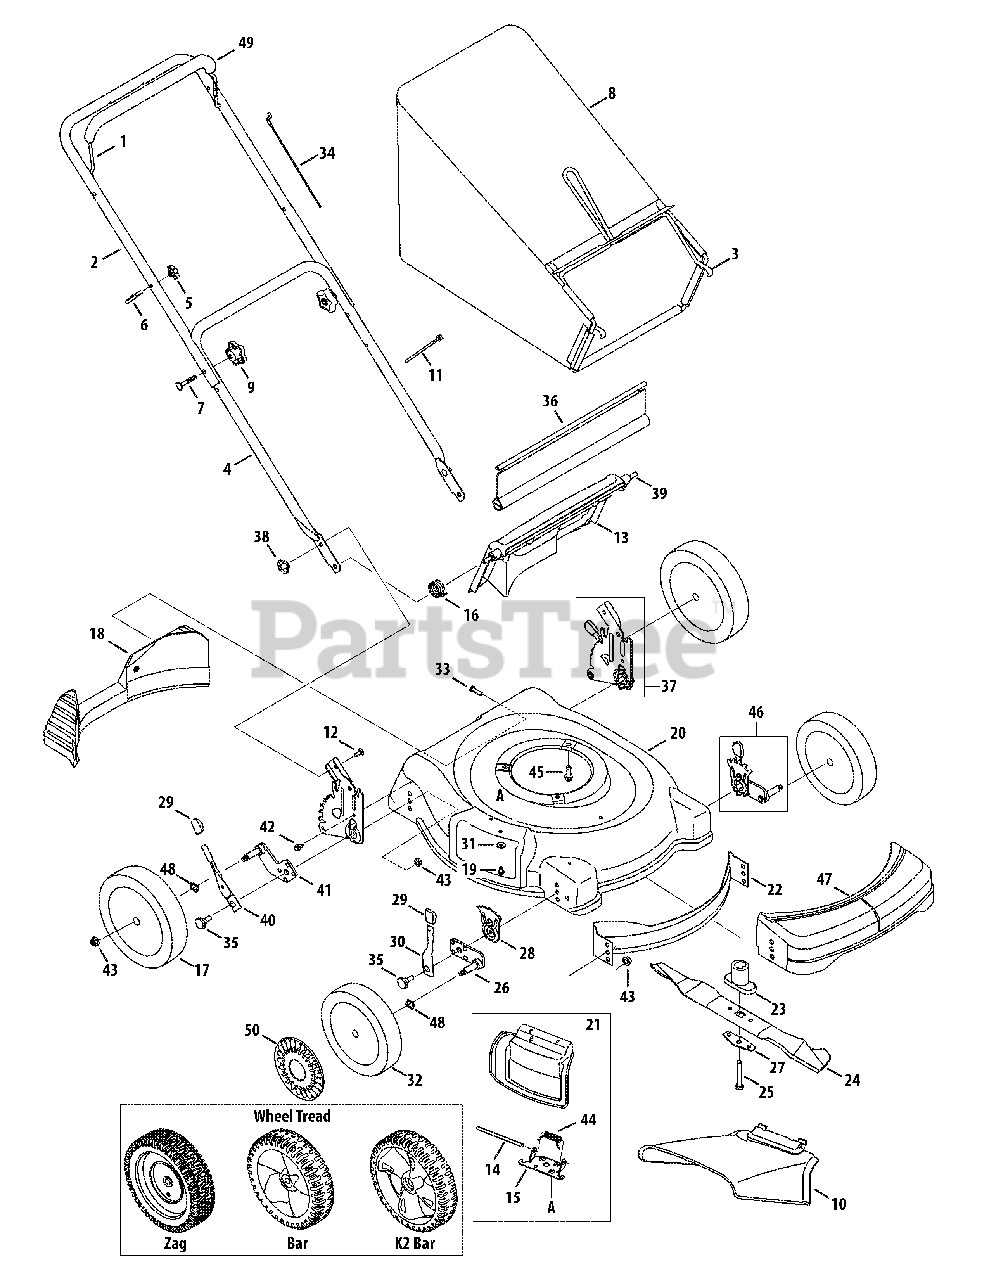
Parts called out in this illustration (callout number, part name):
1	Blade Control Handle
2	Upper Handle
4	Lower Handle
5	Wing Nut
6	Rope Guide
7	Carriage Bolt ,5/16-18 x 2
8	Grass Bag - Black
9	Hand Knob
10	Side Chute
11	Cable Tie
12	Carriage Bolt ,1/4-20
13	Rear Discharge Door
14	Hinge Pin
15	Deflector Chute Adaptor
16	Torsion Spring - RH
17	Rear Wheel, 8 x 2.125, Zag
18	Rear Baffle
19	Screw, 1/4-20 x .500
20	Deck - 21"
21	Hinged Mulch Plug Assembly
22	Front Baffle
23	Blade Adapter, #6 x 2.15
24	Mulching Blade
25	Hex Screw , 3/8-24 x 2.5
26	Pivot Arm Assy RH (8" wheel)
26	Pivot Arm Assy LH (8" wheel)
27	Blade Bell Support
28	Front Adjustment Plate
29	Adjustment Lever Knob
30	Spring Lever Assembly
31	Bell Washer
32	Front Wheel, 8 x 2.125, Zag
33	Screw, 1/4-15 x 1.000
34	Control Cable 40"
34	Control Cable 53"
35	Shoulder Screw
36	Trailshield
37	Rear Handle Bracket Assy. - LH
37	Rear Handle Bracket Assy. - RH
38	Wing Nut, 1/4-20
39	Rear Door Pivot Rod
40	Spring Lever
41	Pivot Arm Assembly - RH
41	Pivot Arm Assembly - LH
42	AB Screw
43	Flange Lock Nut, 3/8-16
44	Torsion Spring
45	TT Sems Screw, 3/8-16 x 1.0
46	Ht. Adj. Assy. Front LH (8" wheel)
46	Ht. Adj. Assy. Front RH (8" wheel)
47	Front Cover
48	Wave Washer
49	Bail Cover - Black
50	Hub Cap
